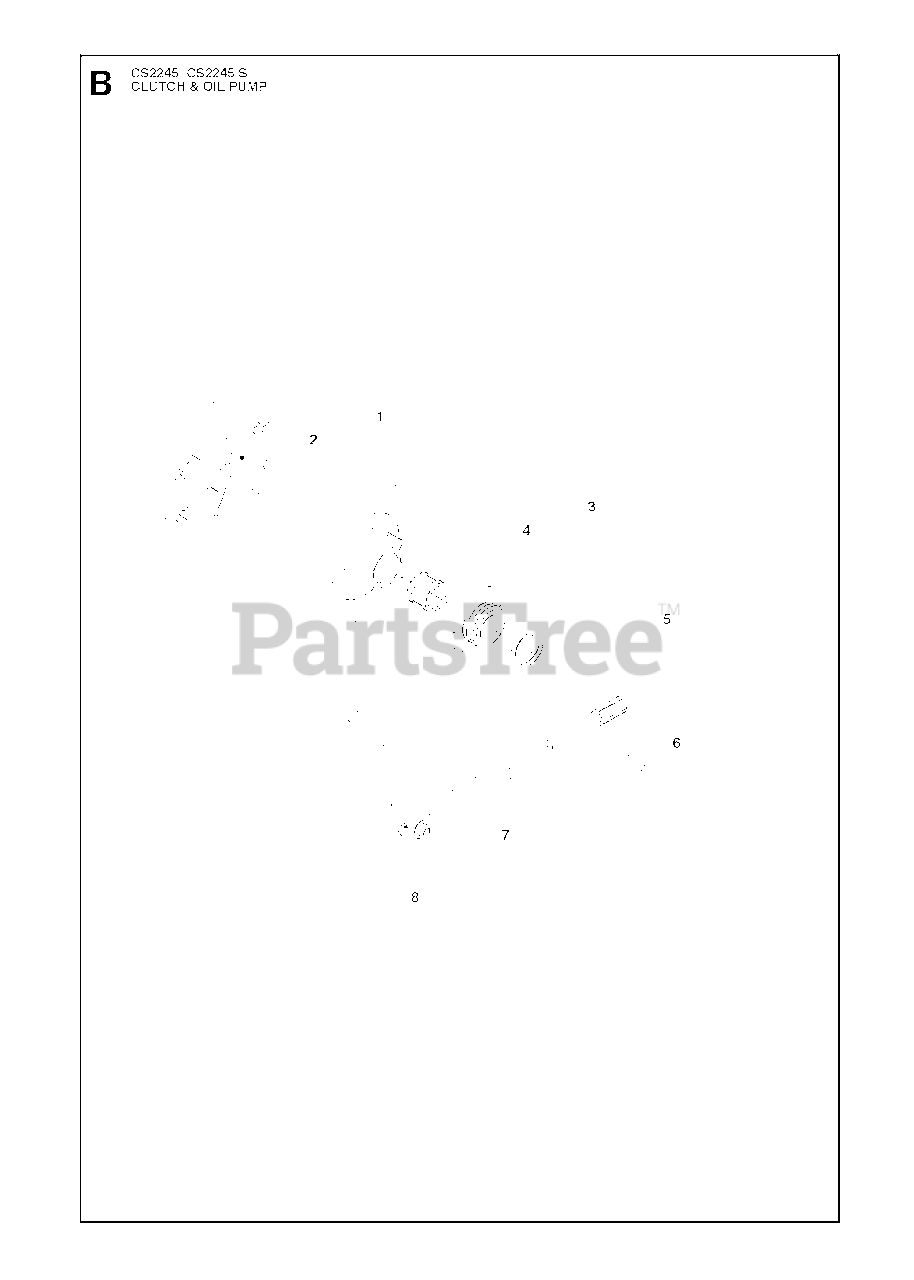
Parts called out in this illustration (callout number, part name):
2	SPRING
3	CLUTCH DRUM
4	NEEDLE BEARING
6	PISTON PUMP
7	PUMP CYLINDER
8	OIL HOSE
